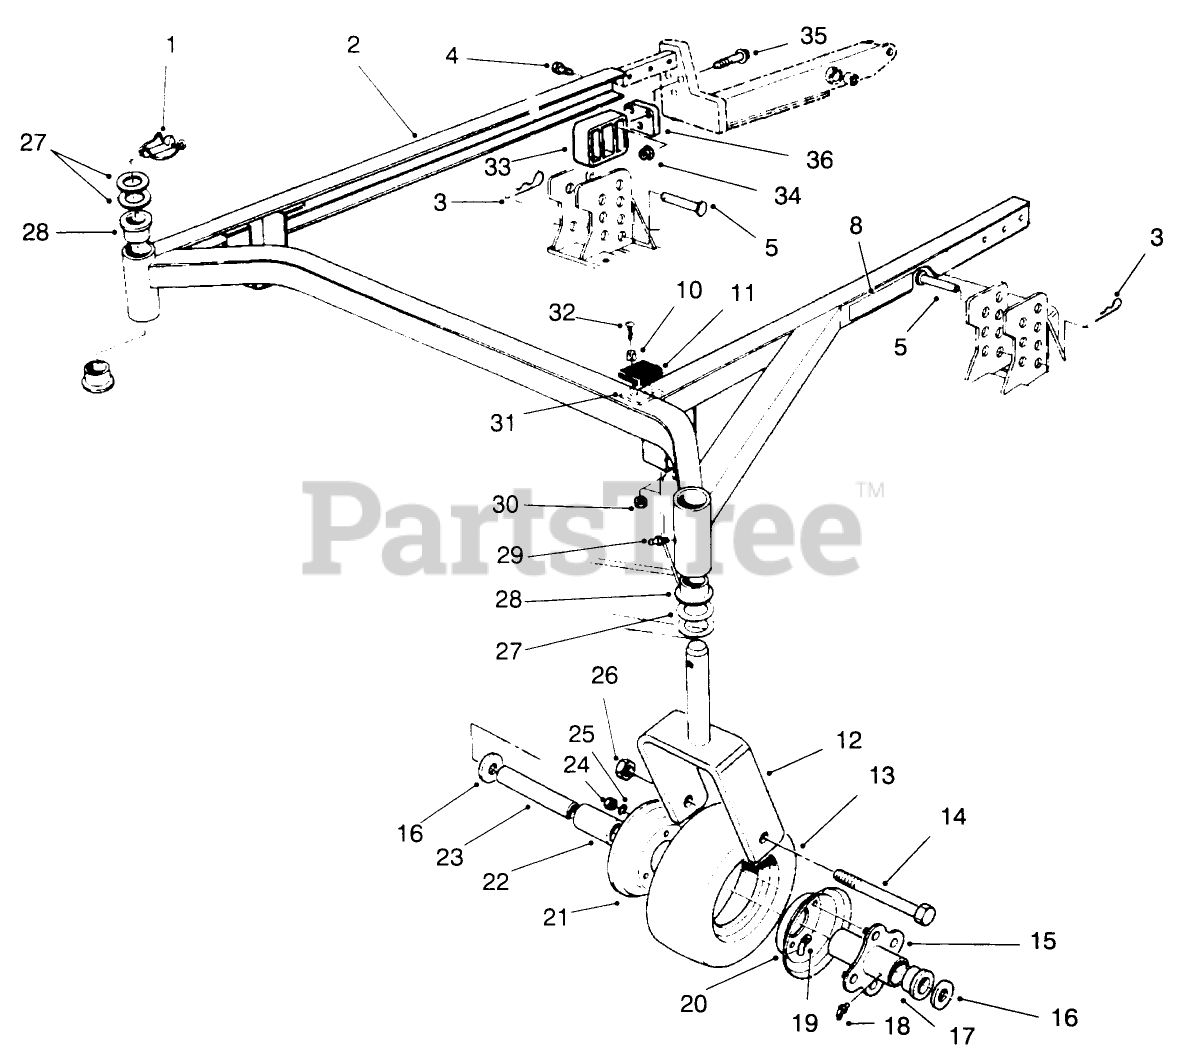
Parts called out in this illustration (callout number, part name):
1	PIN-LYNCH
2	Frame-Deck Suspension (Incl. Ref. #28, 29)
3	PIN-HAIR
4	SCREW-HH
5	PIN-CLEVIS
8	DECAL-HOC, LH
10	SPACER
11	CUSHION-RUBBER
12	Castor Fork
14	SCREW-HH
15	HUB-CENTER
16	WASHER-FLAT
17	BEARING-OUTSIDE
18	FITTING-LUBE, 45 DEG
19	TUBE-INNER (W/VALVE)
20	FEMALE WHEEL HALF
21	MALE WHEEL HALF
22	BEARING-ROLLER
23	SPANNER-TIRE
24	NUT-HEX
25	WASHER-LOCK
26	NUT-HEX
27	WASHER-THRUST
28	BUSHING
29	FITTING-GREASE
30	NUT-LOCK, NI
31	SHIM-CUSHION
33	Cradle-Rear
34	NUT-FLANGE
35	SCREW-HHF, WHIZ
36	Spacer
